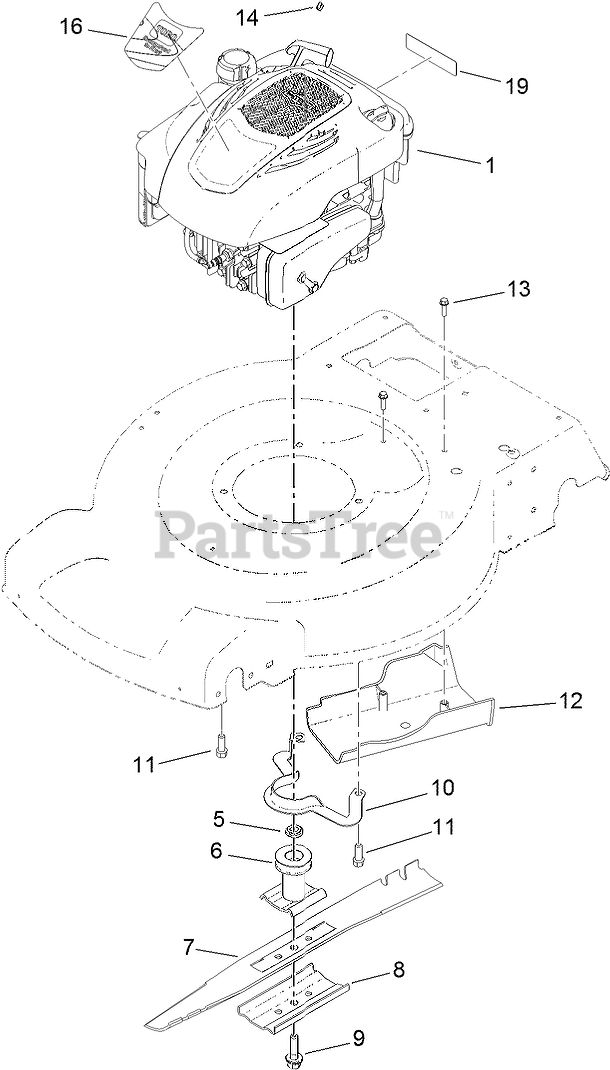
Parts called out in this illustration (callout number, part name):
5	Spacer-Driver
6	DRIVER-BLADE
7	BLADE-22 INCH
8	SUPPORT-BLADE
9	BOLT-BLADE
10	Guide-Belt
11	SCREW-TAPTITE
12	COVER-BELT
13	SCREW-HWH
14	STOP-ROPE
16	DECAL-SHROUD
19	DECAL-ARRESTER, SPARK
